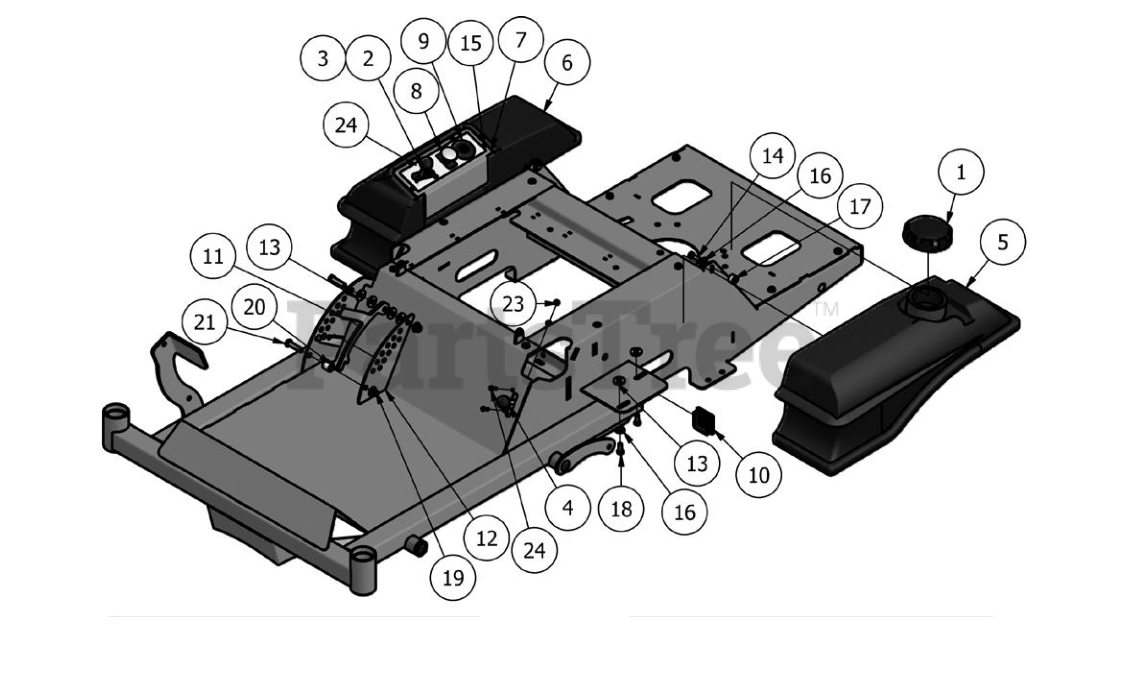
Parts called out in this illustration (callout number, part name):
2	Throttle Lever W/Choke 26Hp
3	Throttle Lever W/Choke 21Hp
4	Brake Lever
5	3 Gallon Fuel Tank
6	Fender Console
7	MZ Control Panel
8	PTO Engager
9	Ignition Switch
10	Ignition Key
11	2x2 Square Plug
12	Deck Level Lock
13	MZ Height Indicator Plate
14	.360ID Plastic Washer
15	5/16-18 x 1 Grade 5 Hex bolt Zinc
16	10-32 x 3/8 Button Socket C/S 18-8 SS
17	5/16 Lock Washer Zinc
18	MZ Tank Spacer
19	5/16-18 x 3/4 Grade 5 Hex bolt Zinc
20	3/8 Nylock Flange Nut
21	3/40D x 1/2ID x 3/4 Spacer
22	3/8-16 x 1-1/2 GR5 Hex Bolt
23	10-24 Nylon Insert Locknut Zinc Orange Nylon
24	10-24 x 3/4 Button Socket C/S 18-8 SS
